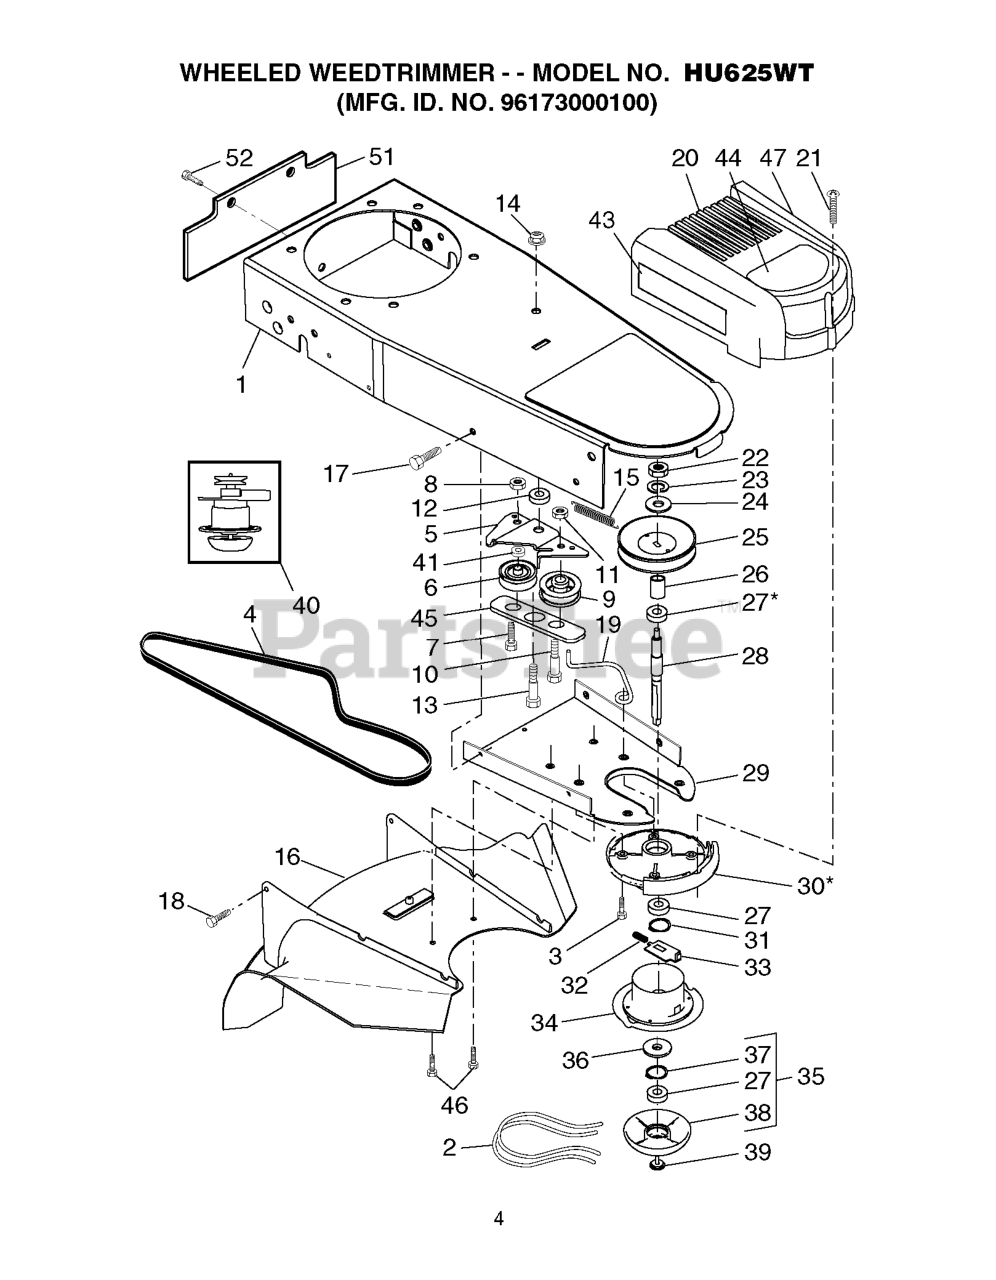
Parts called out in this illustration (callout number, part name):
1	HOUSING.CHASSIS ASM.MID.ORANGE
2	LINE.BUND.18PC
3	BOLT.HEX.HDWSH.5/16-18X1.00
4	BELT-V.STRING TRIMMER.
5	RP.BRACKET.IDLER.TRIMMER.WHEEL
6	PULLEY.V-GROOVE.IDLER
7	BOLT, HEX HEAD 3/8-16 X 1.25
8	LOCKNUT
9	IDLER PULLEY
10	SHOULDER BOLT
11	NUT.CENTERLOCK.5/16-
12	SPACER.IDLER.BRACKET
13	BOLT SHOULDER 3/8 -16X1
14	NUT.HEX.FLANGE.3/8-16.LOCKNUT
15	SPRING.RETURN.WHEELED.TRIMMER
16	DEFLECTOR, BOTTOM
17	SCREW 14-20 X 5/8
19	KEEPER.BELT.STRING.TRIMMER
20	COVER, CHASSIS, TOP
21	SCREW.SLOT.TORX.
22	NUT
23	LOCKWASHER
24	WASHER, FLAT 3/8
25	PULLEY.SPINDLE.WHEELED.TRIMMER
26	SPACER, PULLEY
27	BEARING
28	JACKSHAFT.WHEELED.TRIMMER
29	CHASSIS.COVER.BOTTOM.BLACK
30	SPINDLE HOUSING ASSEMBLY
31	RING, RETAINING, EXTERNAL,
32	SPRING.1.5".COMPRESSION
33	PLATE.LOCKING.WHEELED.TRIMMER
34	CARRIER PLATE ASSEMBLY
35	MOW BALL ASSEMBLY
36	COVER, BEARING
37	RING, RETAINING, INTERNAL,
38	MOW BALL
39	BOLT, MOW BALL
40	ASM.ADJUSTABLE.SPINDLE.WHLD.TR
41	SPACER (2 2MC)
43	DECAL, INSTRUCTION
44	DECAL.HSG.TRIMMER.WHEELED.HUSQ
45	BRACKET.BELT.KEEPER.BLACK
47	DECAL.INSTRUCTION.CE.TRIM.STRG
51	SKIRT.REAR.WHEELED.TRIMME(3 2)
